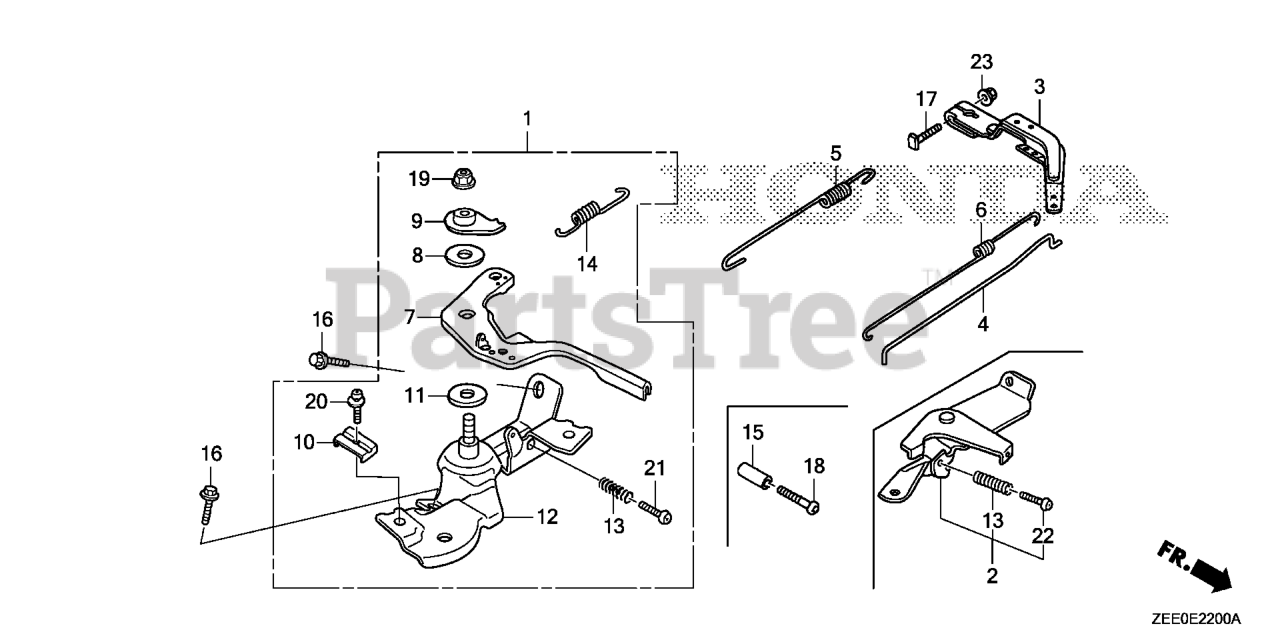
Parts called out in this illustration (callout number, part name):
1	CONTROL ASSY. (REMOTE)
3	ARM, GOVERNOR
4	ROD, GOVERNOR
5	SPRING, GOVERNOR
6	SPRING, THROTTLE RETURN
7	LEVER, CONTROL
8	SPRING, LEVER
9	WASHER, CONTROL LEVER
10	HOLDER, CABLE
11	SPACER, CONTROL LEVER
12	BASE, CONTROL
13	SPRING, CONTROL ADJUSTING Use from Engine SN 2327377.
14	SPRING, CABLE RETURN
15	COLLAR, STOPPER
16	BOLT, FLANGE (6X12) (CT200)
17	BOLT, GOVERNOR ARM
18	SCREW, RECESSED (5X25)
19	NUT, SELF-LOCK (6MM)
20	SCREW, PAN (5X16)
21	SCREW, PAN (5X25)
23	NUT, FLANGE (6MM)
